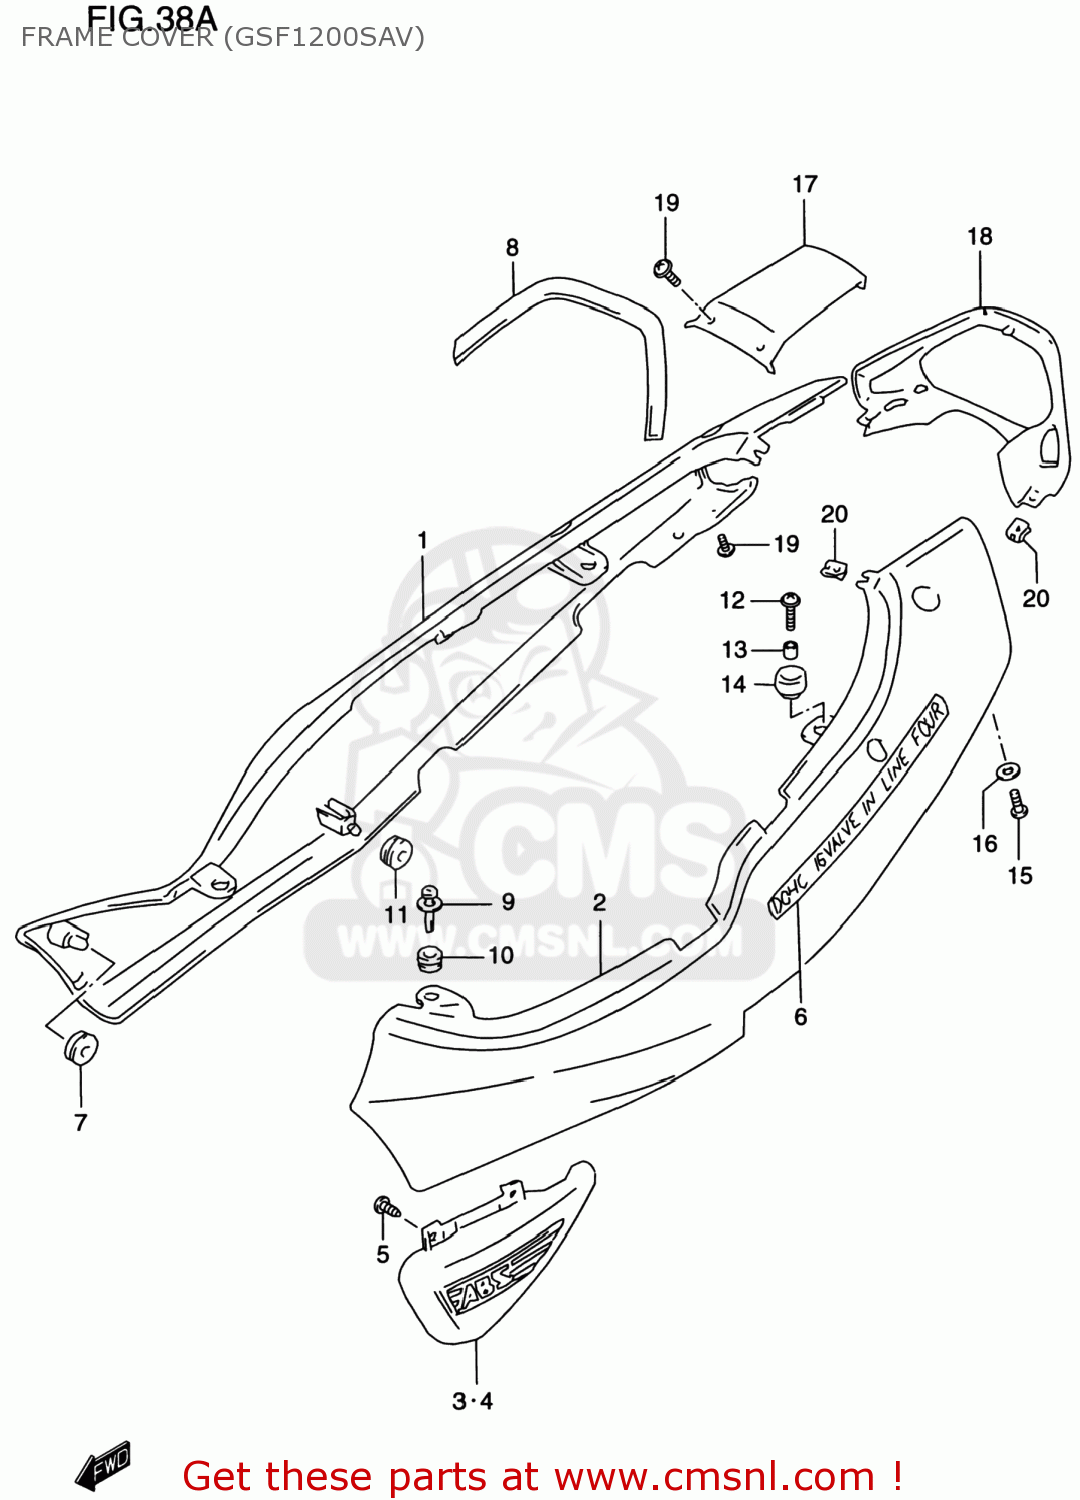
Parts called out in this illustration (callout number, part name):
1	COVER COMP,FRAME,RIGHT
2	COVER,FRAME,L(BLACK)
3	COVER,FRAME LWR,R
4	COVER,FRAME LWR,L
5	SCREW
6	EMBLEM,FRAME COVER
7	CUSHION,FRAME COVER FR
8	CUSHION,FRAME COVER UPR
9	CLIP
10	CUSHION
11	CUSHION
12	SCREW(6X20)
13	SPACER(6.5X10X9.4)
14	CUSHION
15	SCREW
16	WASHER(6.3X16X1.5)
17	COVER,FRAME CTR
18	COVER,FRAME RR
19	SCREW
20	NUT
